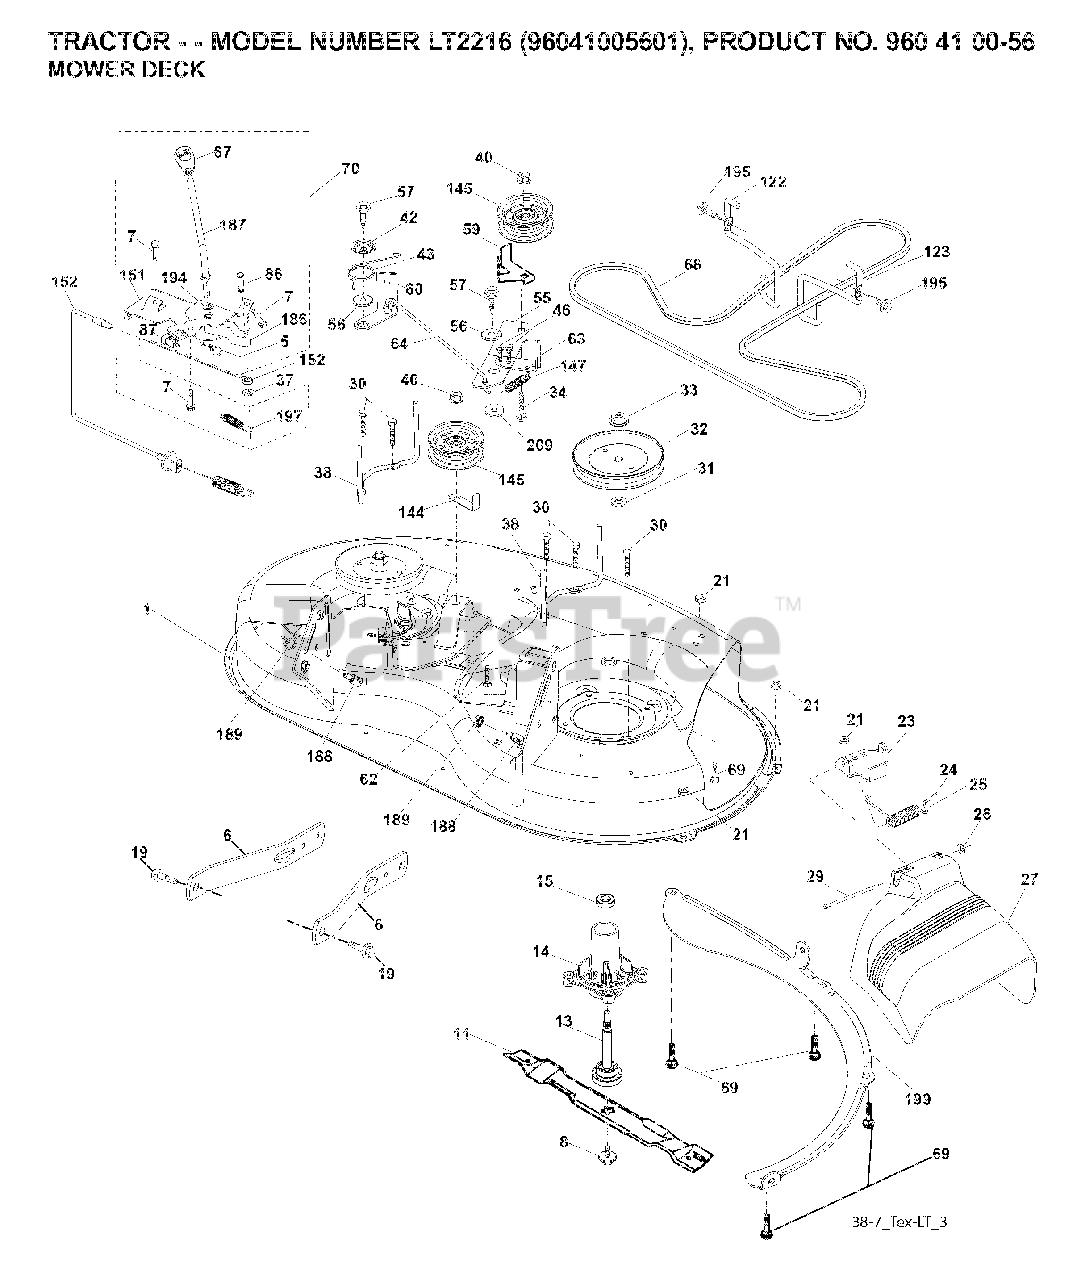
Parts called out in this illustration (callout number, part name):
5	RETAINER-SPRNG RB
6	ARM.SUSPENSION.MOWER.R
7	SCREW
8	BOLT.WASHER.ASM.7/16-2
11	BLADE 38" PREMIUM
13	SHAFT.ASM.MDRL.N/GREASE.38
14	HOUSING MANDREL
19	BOLT.SHOULDER
21	LOCKNUT
23	BRKT.DEFLECTOR.38"2005+
24	CAP-SLEEVE LT
25	SPRING.TORSION.DEFLECT
26	NUT PUSH M
29	ROD.HINGE
30	SCREW, WASHER HEAD
31	WASHER.SPACER.MANDREL
32	PULLEY.MANDREL.5.0.PD.38"
33	NUT.FLANGE.LOCK.TOP
34	BOLT.3/8-16X1.50
38	KEEPER BELT LH MANDREL
40	NUT LOCK FLG 3/8-16 UNC
42	SPRING.TORSION.BRAKE
43	SRPING.TORSION.RETAINE
46	SCREW.1/4-20X5/8
55	IDLER.ARM
56	SPACER.RETAINER
57	SCREW 3/8-16X1
59	GUARD, BELT
60	ARM BRAKE MOWER RH 38"
62	BOLT.3/8-16X1.50
63	ARM BRAKE MOWER RH
64	LINK BRAKE
67	HANDLE.CLUTCH.CABLE.LT
69	BOLT
70	CLUTCH.ASM.MANUAL.LT.TEX
86	PIN ATTACHMENT CABLE
87	SWITCH.INTRLCK.CLUTCH.
122	KEEPER BELT ENGINE LH
123	KEEPER BELT RH
144	KEEPER BELT
145	PULLEY.IDLER.48"PRIMARY
147	SPRING RETURN
151	BRACKET.CLUTCH CABLE.TEX
152	CLUTCH CABLE
186	ARM ACTUATOR
188	STUD.FASTNER.W/ANTI-ROTATE
189	NUT LOCK HEX FLANGE 5/16-18
194	BEARING.CONTROL.LEVER.CLUTCH
195	SCREW, 3/8-16X3/4
197	SPRING.PLUNGER.ACTUATOR
199	BAFFLE VORTEX
209	WASHER 12/32X2X10GA
